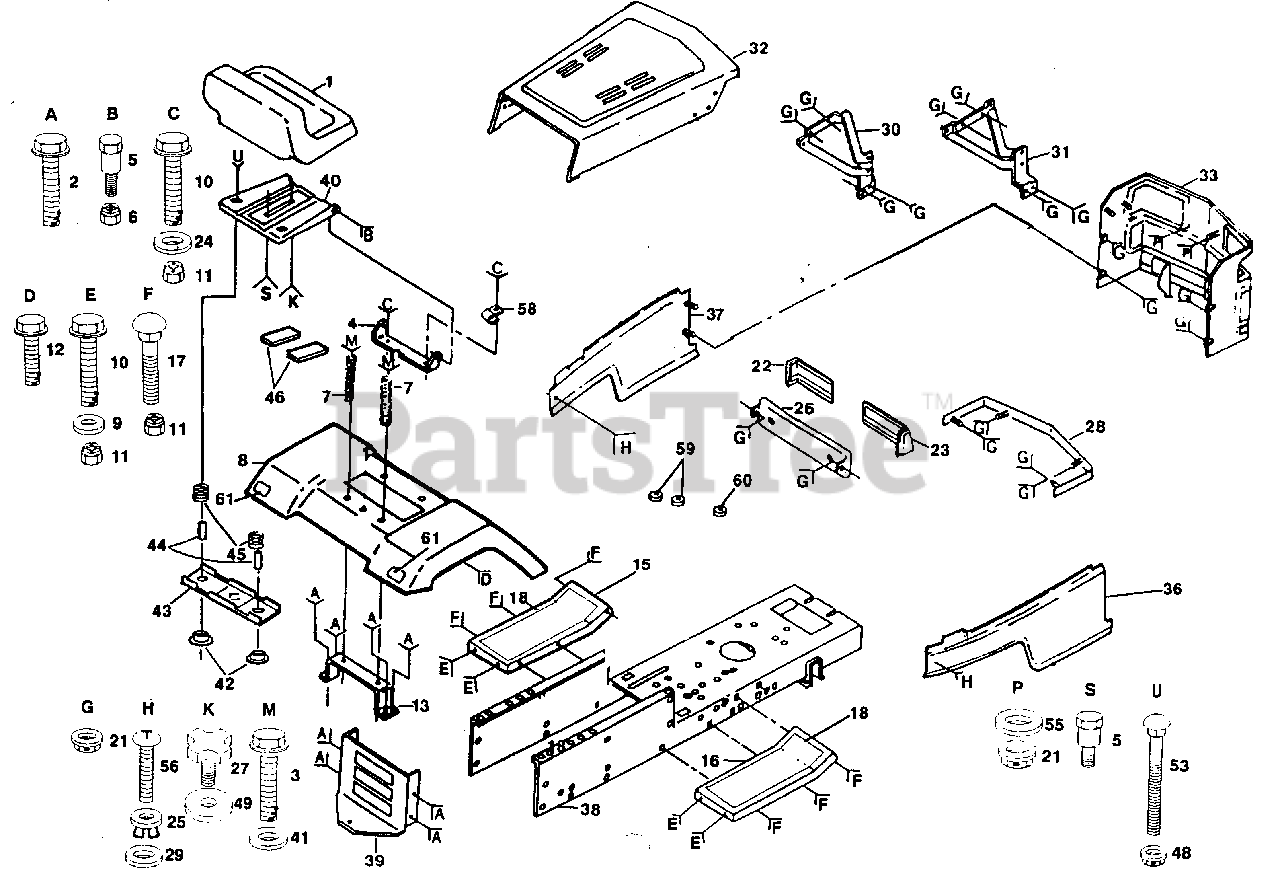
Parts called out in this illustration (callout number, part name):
1	Seat (AYP part number)
2	Screw, Hex,Washer Thread Rolling 3/8-16 x 3/4 Type TT (AYP part number)
3	Screw, Hex,Washer Thread Rolling 3/8-16 x 1 (AYP part number)
4	Bracket, Pivot, Seat (AYP part number)
5	Bolt, Shoulder 5/16-18 (AYP part number)
6	Nut, Crownlock 5/16-18
7	Spring, Seat (AYP part number)
8	Fender (AYP part number)
9	Washer 13/32 x 13/16 x 12 Ga. (AYP part number)
10	Bolt, Hex,Washer Thread Rolling 3/8 (AYP part number)
11	Nut, Crownlock 3/8 - 16
12	Screw, Hex,Washer Thread Rolling 3/8-16 x 12 (AYP part number)
13	Bracket, Fender (AYP part number)
15	Footrest, L.H. (AYP part number)
16	Footrest, R.H. (AYP part number)
17	Bolt, Carriage 3/8-16 x 3/4 (AYP part number)
18	Pad, Footrest (AYP part number)
21	Pal Nut 1/4-20 (AYP part number)
22	Lens, L. H. (AYP part number)
23	Lens, R.H. (AYP part number)
24	Washer 13/32 x 3/4 x 10 Ga. (AYP part number)
25	Retainer (AYP part number)
26	Bezel, Headlight (AYP part number)
27	Knob, 1/2" Seat (AYP part number)
28	Strap Assembly Grill (AYP part number)
29	Plastic Grommet (AYP part number)
30	Hinge, Hood, L.H. (AYP part number)
31	Hinge, Hood, R.H. (AYP part number)
32	Hood Assembly (AYP part number)
33	Grill Assembly
36	Side Panel, R. H. (AYP part number)
37	Side Panel, L. H. (AYP part number)
38	Chassis Assembly (AYP part number)
39	Drawbar (AYP part number)
40	Pan, Seat (AYP part number)
41	Washer 13/32 x 1 x 14 Ga. (AYP part number)
42	Bushing, Snap (AYP part number)
43	Bracket, Switch Mount (AYP part number)
44	Spacer, Split (AYP part number)
45	Spring, Compression (AYP part number)
46	Strip, Foam (AYP part number)
48	Nut, Hex Flange 1/4-20 (AYP part number)
49	Washer 17/32 x 1-3/16 x 12 Ga. (AYP part number)
53	Bolt, Carriage 1/4-20 x 1-1/4 (AYP part number)
55	Washer 9/32 x 3/4 x 16 Ga. (AYP part number)
56	Screw, Special (AYP part number)
58	Clip (AYP part number)
59	Grommet, Split (AYP part number)
60	Grommet (AYP part number)
61	Reflector, Taillight (AYP part number)
